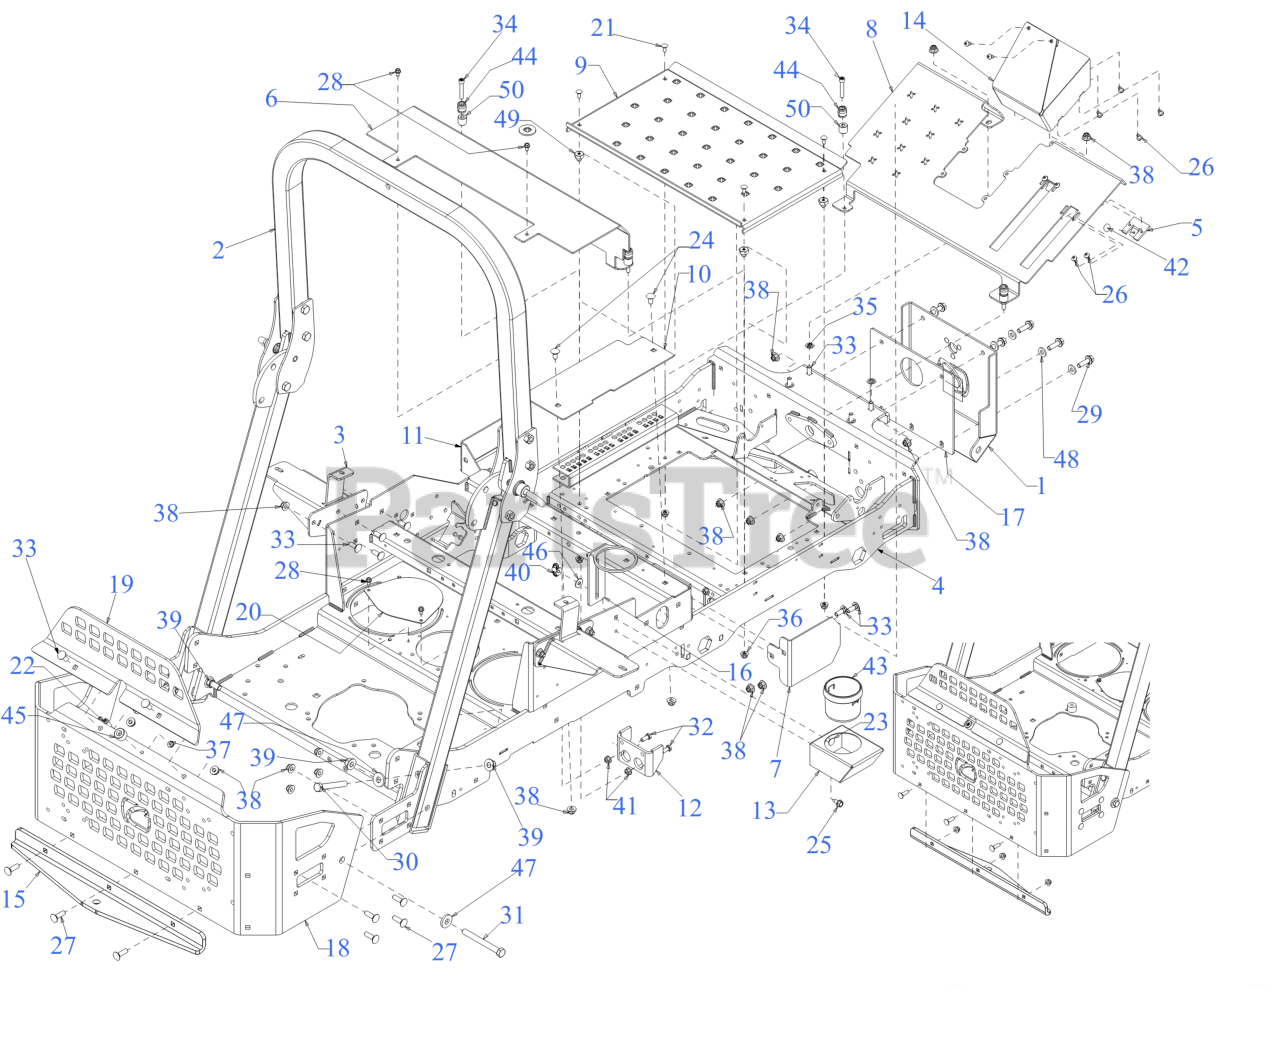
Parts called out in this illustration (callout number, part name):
2	PRO Z ROPS KIT
3	FUEL TANK MOUNT
4	FRAME
5	REVERSE PEDAL STOP BRACKET
6	SEAT BOX COVER
8	FRONT PEDAL COVER
11	SEAT BOX END COVER (LH)
12	FRONT DECK LIFT MOUNTING BRACKET
17	FRONT MOUNTING PLATE SPACER
18	BUMPER (LOWER RR)
19	BUMPER (UPPER RR)
20	FRAME COVER PLATE
21	CARRIAGE BOLT 1/4-20 x .62
22	MACHINE SCREW 1/4-20:1
23	CARRIAGE BOLT 5/16-18 x 1.00
24	CARRIAGE BOLT 3/8-16 x .750 GR5
25	SCREW 5/16-18 x .750
26	SCREW 1/4-20 x .5
27	CARRIAGE BOLT 3/8-16 X1.25 GR5
28	SCREW 1/4-20 X.500
29	SCREW 3/8-16 x 1.25 GR5
30	HEX SCREW 1/2-13 x 3.50
31	SCREW 1/2-13 x 4.5 GR 5
32	SCREW 5/16-18 x .75 GR5
33	CARRIAGE BOLT 3/8-16 x 1.00 GR5
34	SCREW 5/16-18X1.75 GR5
36	FLANGE LOCK NUT 5/16-18
37	FLANGE LOCK NUT
40	WING NUT 5/16-18
41	HEX FLANGE NUT
42	RATCHET CLIP
44	RADIAL BUMPER
46	FLAT WASHER
47	FLAT WASHER .531 x 1.25 x .181
48	FLAT WASHER
49	SHOULDER SPACER
